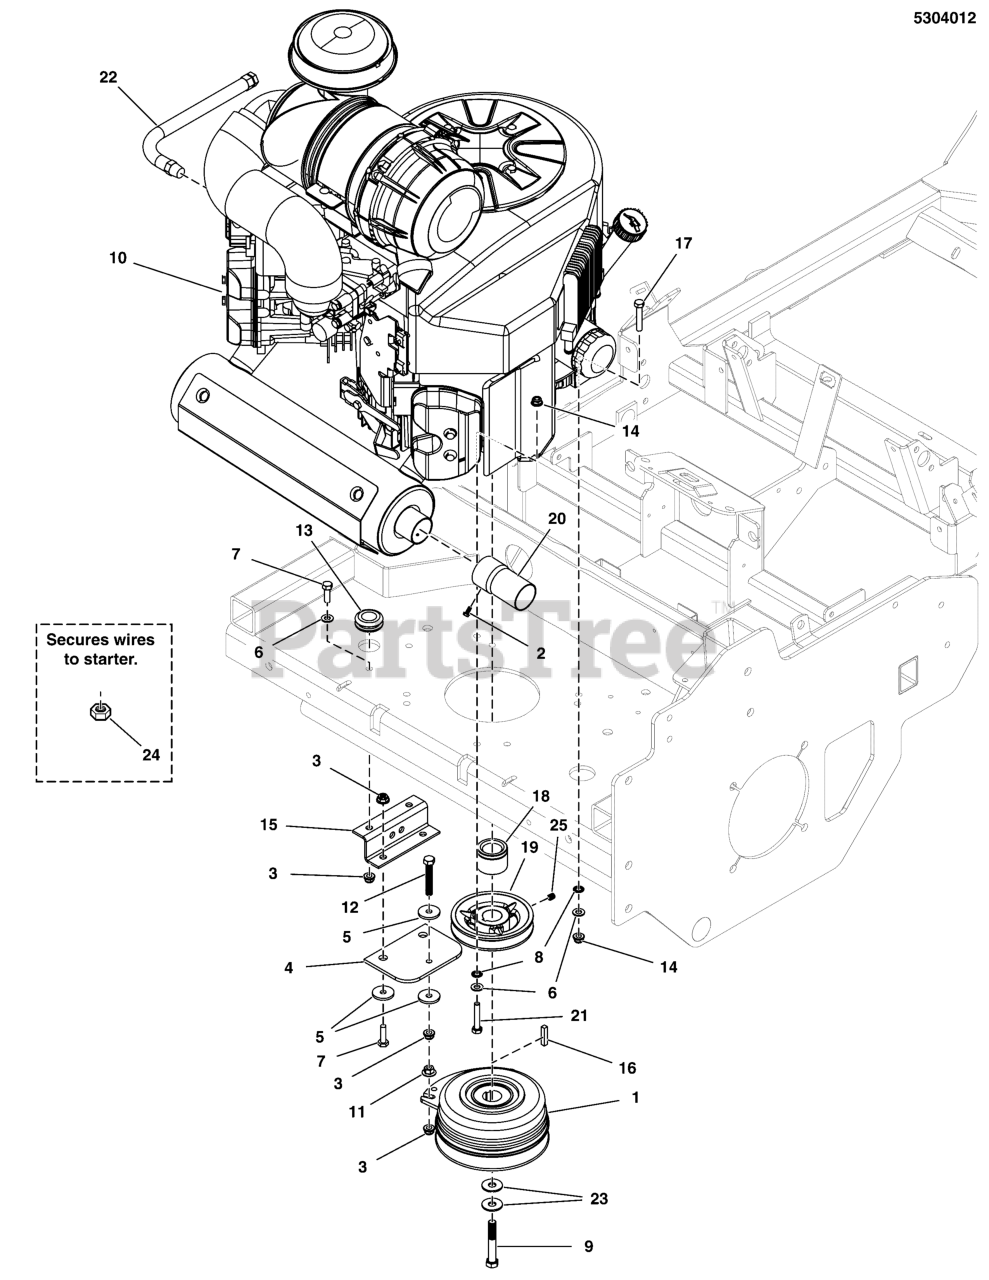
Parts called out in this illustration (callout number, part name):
1	CLUTCH, WARNER, 200 ft lbs - 1.13"
2	SCREW,SELF-TAP,#8-32 X 3/8,WASH HEX, CZ
3	NUT, 5/16-18 HEX NYLOCK FLANGE
4	CLUTCH ANCHOR PAD
5	WASHER, .34 X 1.25 X 10 GA
6	WASHER, 5/16" SAE
7	BOLT, 5/16-18 X 1 GD5 CZ
8	WASHER, 5/16 INT. TOOTH LOCK
9	BOLT, CRANKSHAFT,7/16-20X2-3/4, GD8
10	ENGINE, 28HP BRIGGS VANGUARD, EFI
11	NUT, 5/16-18 HEX SERRATED FLANGE (LARGE)
12	BOLT, 5/16-18 X 2-1/4 TFL, GD5 YZ
13	GROMMET, 7/8"ID, 1/4" THICK STK
14	NUT, 5/16-24, TOP LOCK FLANGE, GD8 PHOS
15	ANCHOR, CLUTCH - BLK
16	KEY, 1/4 SQ X 1-1/4
17	BOLT, 5/16-24 X 1-1/2, GD8, PHOS
18	SPACER, 1.13 X 1.75 X 1.35, CZ
19	PULLEY, 4.75 OD X 1-1/8 BORE, BC-48
20	EXTENSION, TAILPIPE, 3", BLACK
21	BOLT, 5/16-24 X 1-3/4, GD8, PHOS
22	HOSE, OIL DRAIN
23	BELLEVILLE WASHER 1.1875 X .442 X .089
24	NUT, 5/16-24 JAM
25	SET SCREW, 5/16-18 X 3/8, KNURL W/ PATCH
